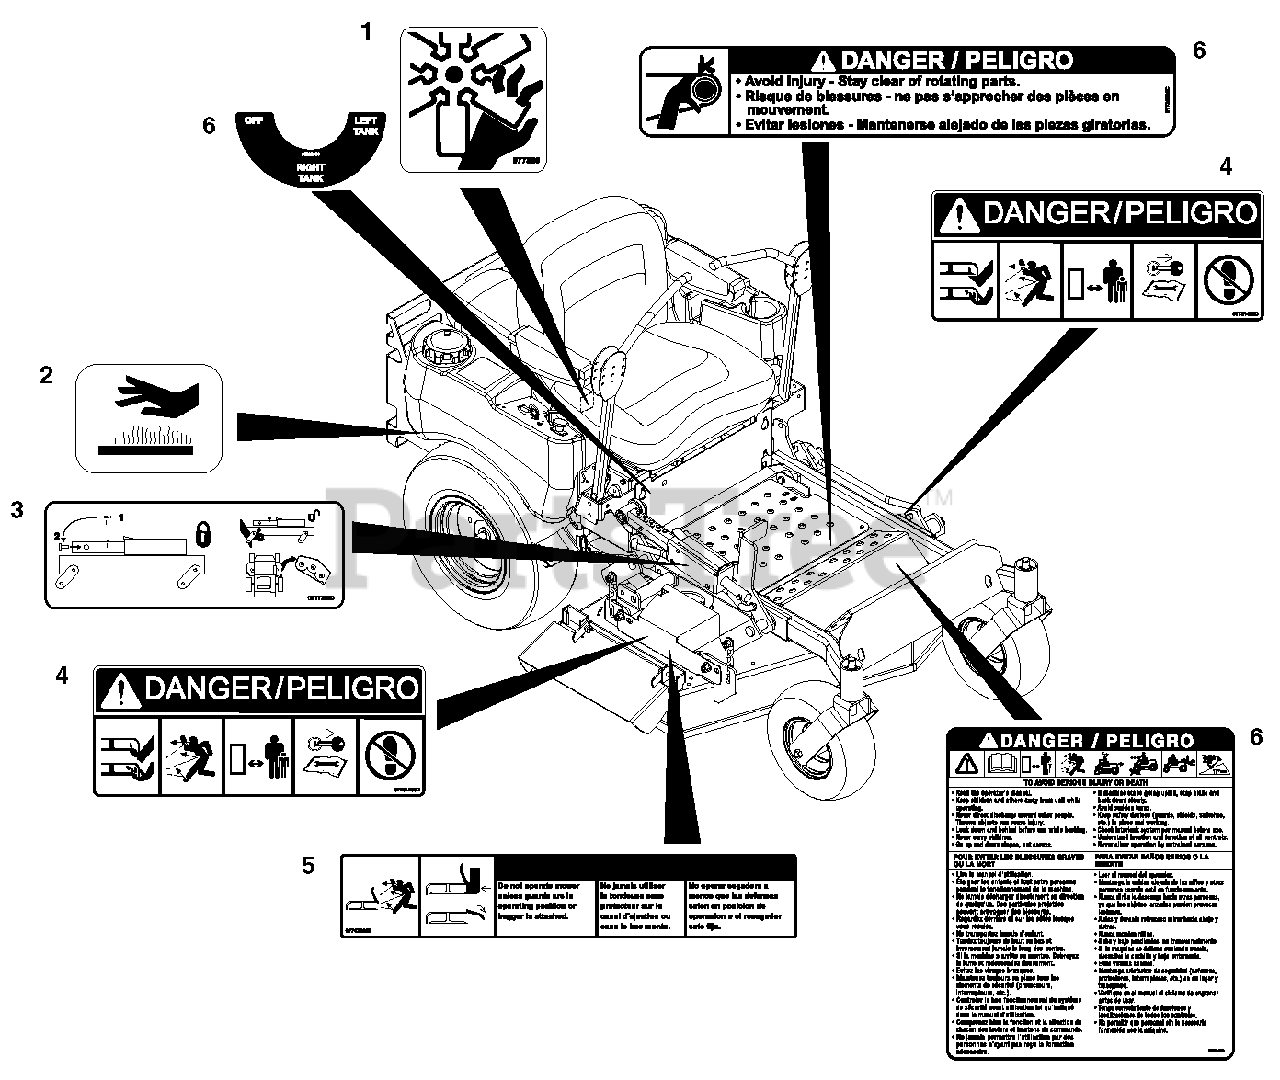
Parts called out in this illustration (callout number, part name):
1	Decal, Danger Fan
2	Decal, Hot Surface
3	Decal, Deck Service
4	Decal, Mower Pan Head Danger
5	Decal, Warning
6	Set, Decal Common Danger/Fuel
